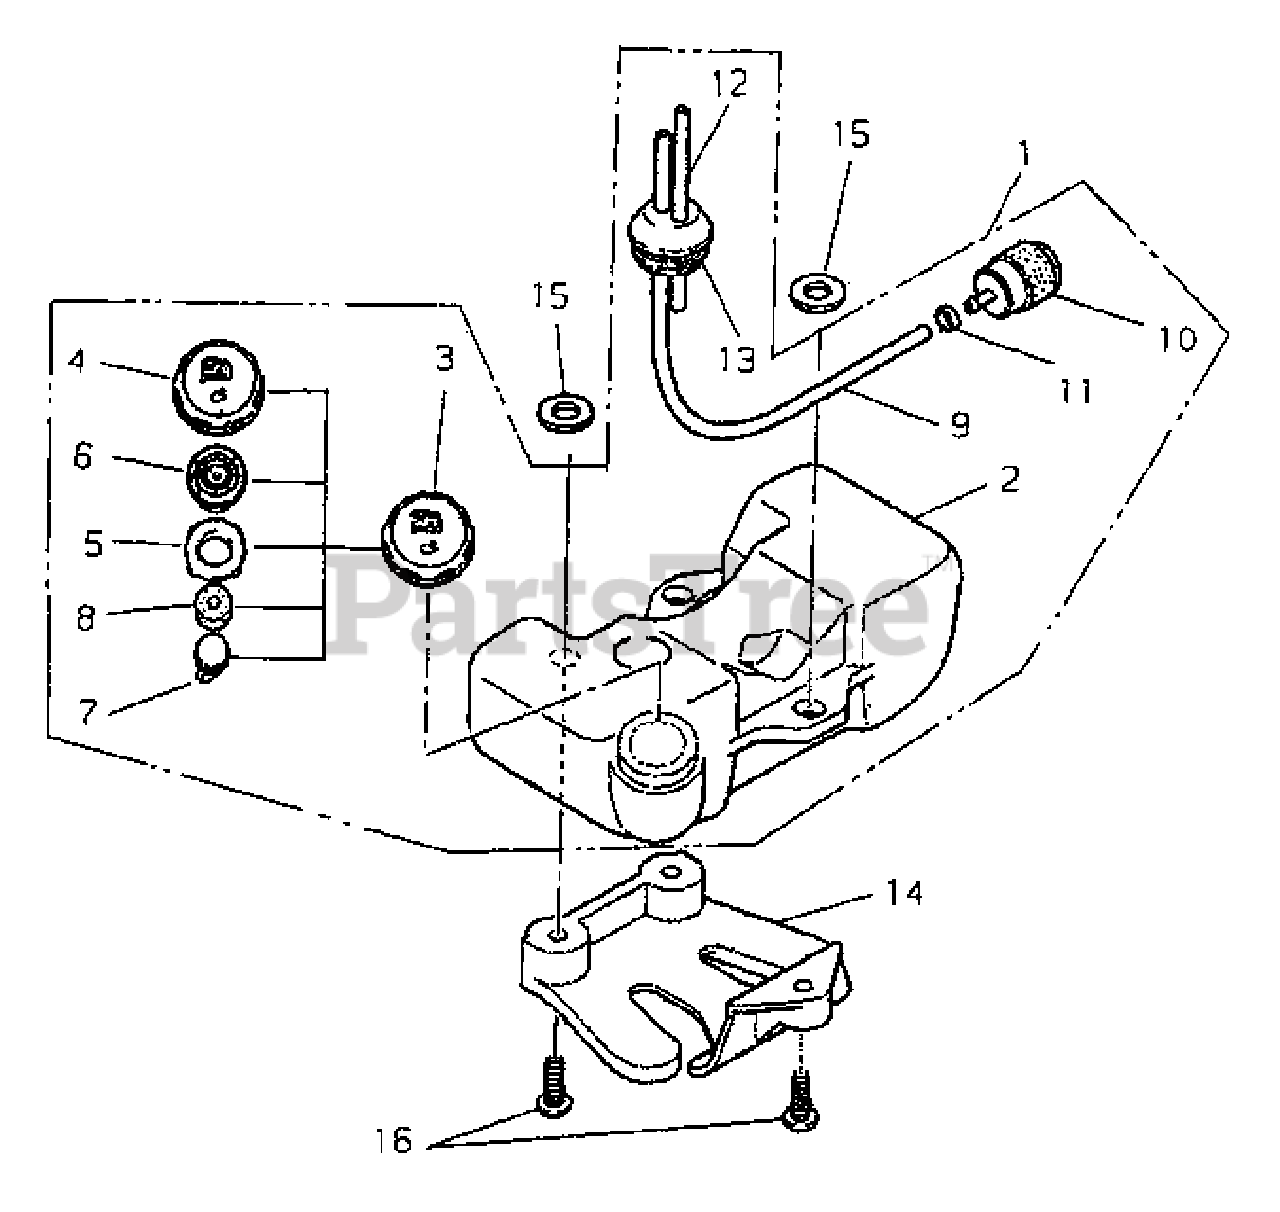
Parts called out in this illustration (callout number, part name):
1	FUEL TANK ASSY
2	TANK, FUEL
3	CAP ASSY
4	CAP, FUEL
5	PACKING
7	CAP
9	PIPE, FUEL
10	FILTER, FUEL
11	CLIP
12	PIPE
13	GROMMET
14	GUARD, FUEL TANK
16	SCREW - TAPPING
